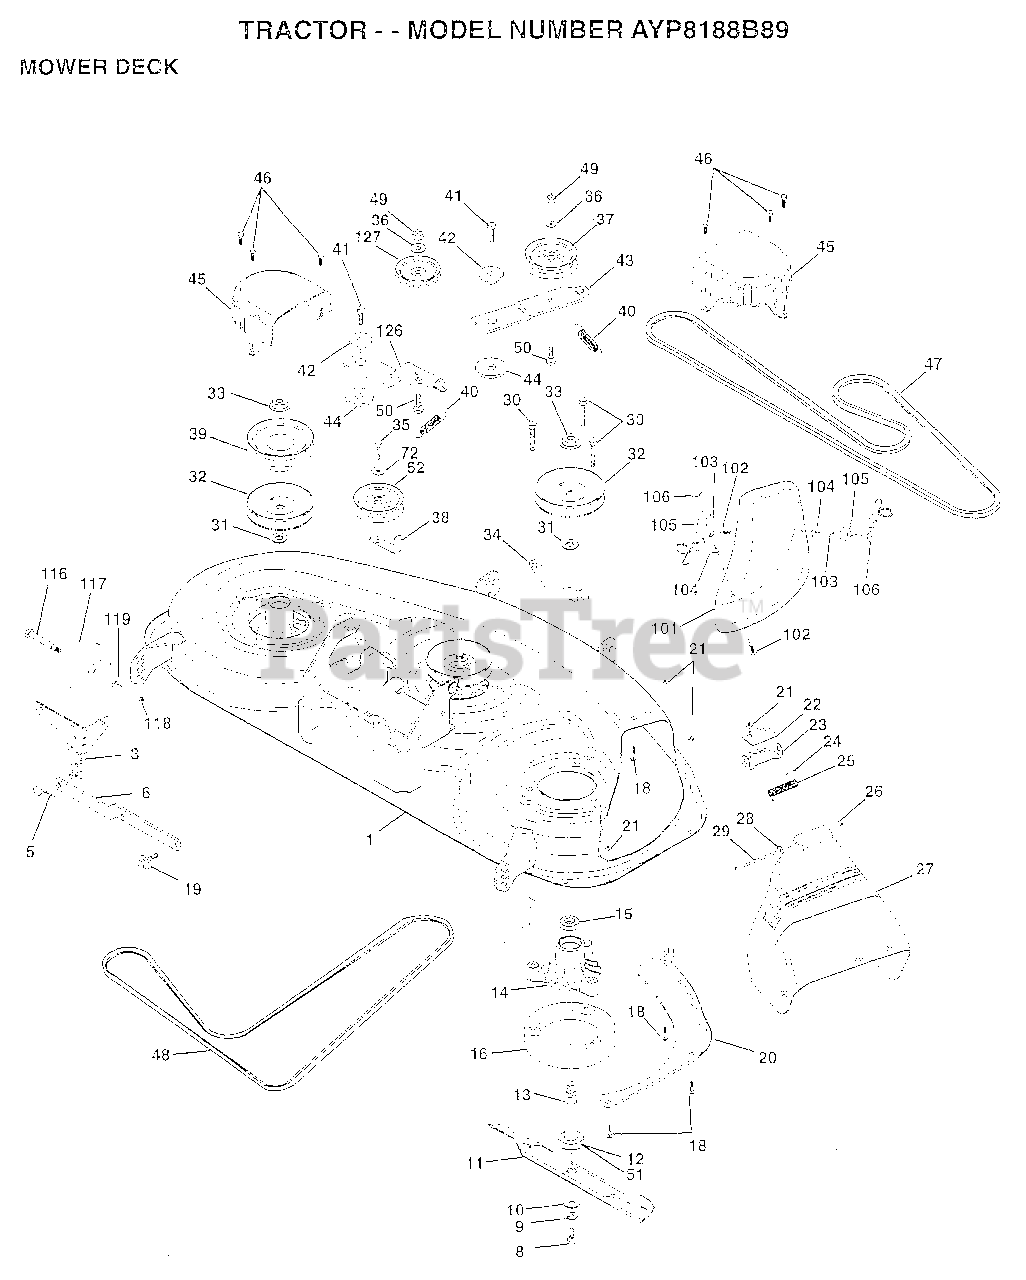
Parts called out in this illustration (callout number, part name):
1	"DECK.ASM.MOWER46"""
3	BRKT.ASM.SW.44/50
8	BLADE BOLT
10	WASHER.HARD.BLADE
11	"BLADE MULCH 46"""
12	BEARING.BALL
13	SHAFT.ASM.W/BRNG
14	HOUSING.MAND.44.V
15	BEARING
16	STRIPPER RND MWR
18	BOLT
19	BOLT SHD 5/16-18
20	BAFFFLE.VORTEX.46
22	STIFFENER BRKT
23	DEFLECTOR BRKT
24	CAP-SLEEVE LT
26	NUT PUSH M
27	SHIELD DEFLECTOR
28	WASHER
29	HINGE ROD
30	"SCREW-THD ROLL,WA"
31	WASHER
32	PULLEY.MAND.36/46
34	ANCHOR.SPRING.46
35	SCREW LT
36	WASHER
37	FLAT IDLER PULLEY
38	"KEEPER BELT,IDLER"
39	PULLEY.DRV.DCK.46
40	"SPRING.SEC.44""VEN"
41	SCREW
42	SPACER RETAINER
43	ARM.IDLER.DECK.46
44	HARDENED WASHER
45	COVER.MANDREL.46
46	SCREW.1/4-20X5/8
47	BELT-V.SEC.46.KEL
48	BELT V PRIM 50
50	BOLT.3/8-16X1.50
51	WASHER.FELT.
52	"PULLEY IDLER,FLAT"
72	WASHER HYT
101	COVER.MULCHING.
102	SCREW
103	LOCKWASHER
104	WASHER #10
105	LATCH ASSY.BAGGER
106	WELDNUT
116	BOLT.SHOULDER
117	WHEEL GAGE DONUT
118	LOCKNUT
119	WASHER
126	ARM.IDLER.PRIM.46
127	PULLEY.IDLER.4.25
